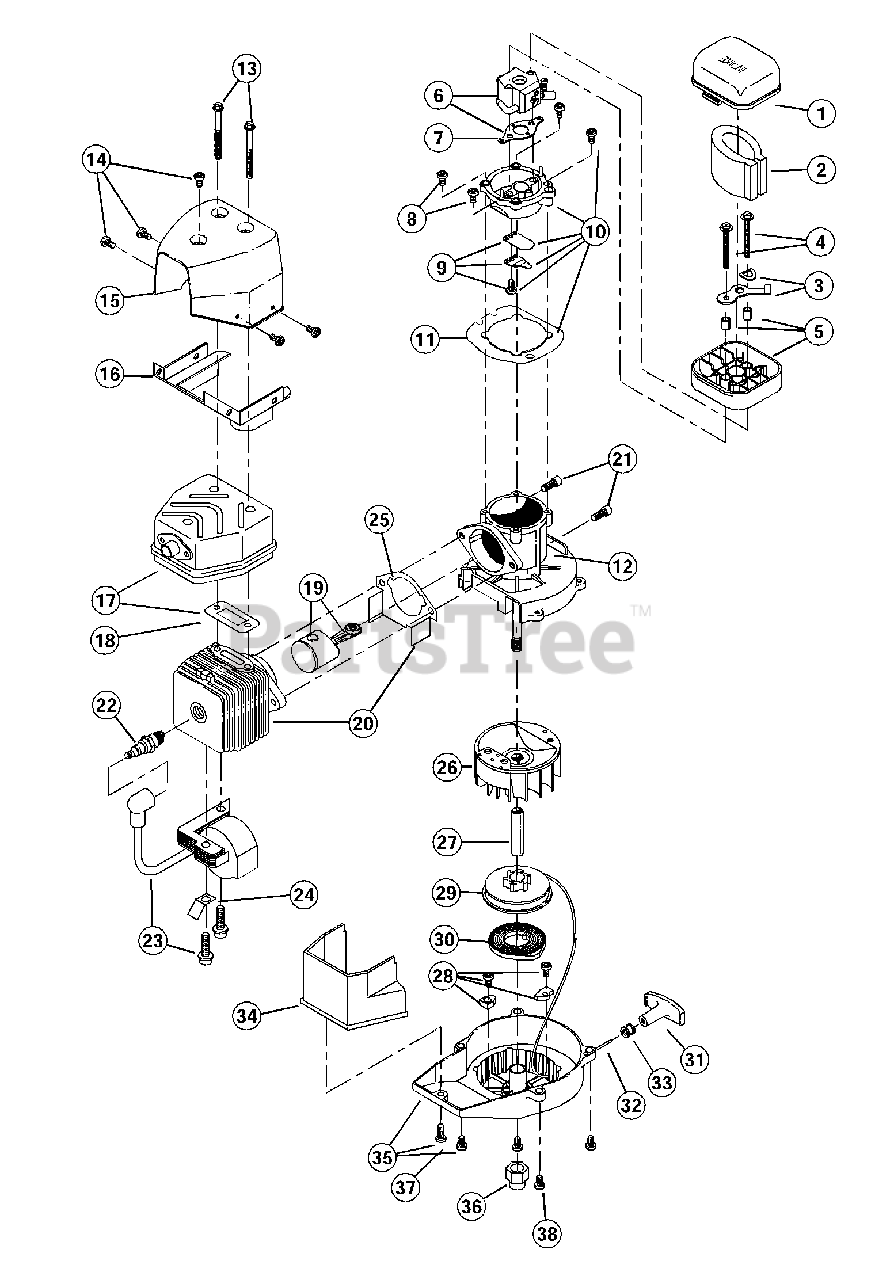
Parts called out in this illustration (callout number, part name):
1	Air Cleaner Cover Assembly
2	Air Cleaner Filter
3	Choke Lever Assembly
4	Mounting Bolts
5	Air Cleaner Base
6	Carburetor Assembly
7	Carburetor Gasket
8	Reed Plate Mounting Screw
9	Reed Assembly
10	Complete Reed Plate Assembly
11	Reed Plate Gasket
12	Crankcase Service Assembly
13	Muffler Mounting Bolts
14	Mounting Screws
15	Upper Heat Shield
16	Lower Heat Shield
17	Muffler Assembly
18	Exhaust Gasket
19	Piston and Rod Assembly
20	Cylinder Assembly
21	Cylinder Bolt
22	Spark Plug
23	Module Assembly
24	Ground Tab
25	Cylinder Gasket
26	Flywheel Assembly
28	Pulley Retainer Assembly
29	Recoil Pulley Assembly
30	Recoil Spring
31	Pull Handle
33	Rope Guide
34	Shroud Extension
35	Starter Housing Assembly
36	Crankshaft Extension
37	Shroud Extension Screw
38	Housing Screw
